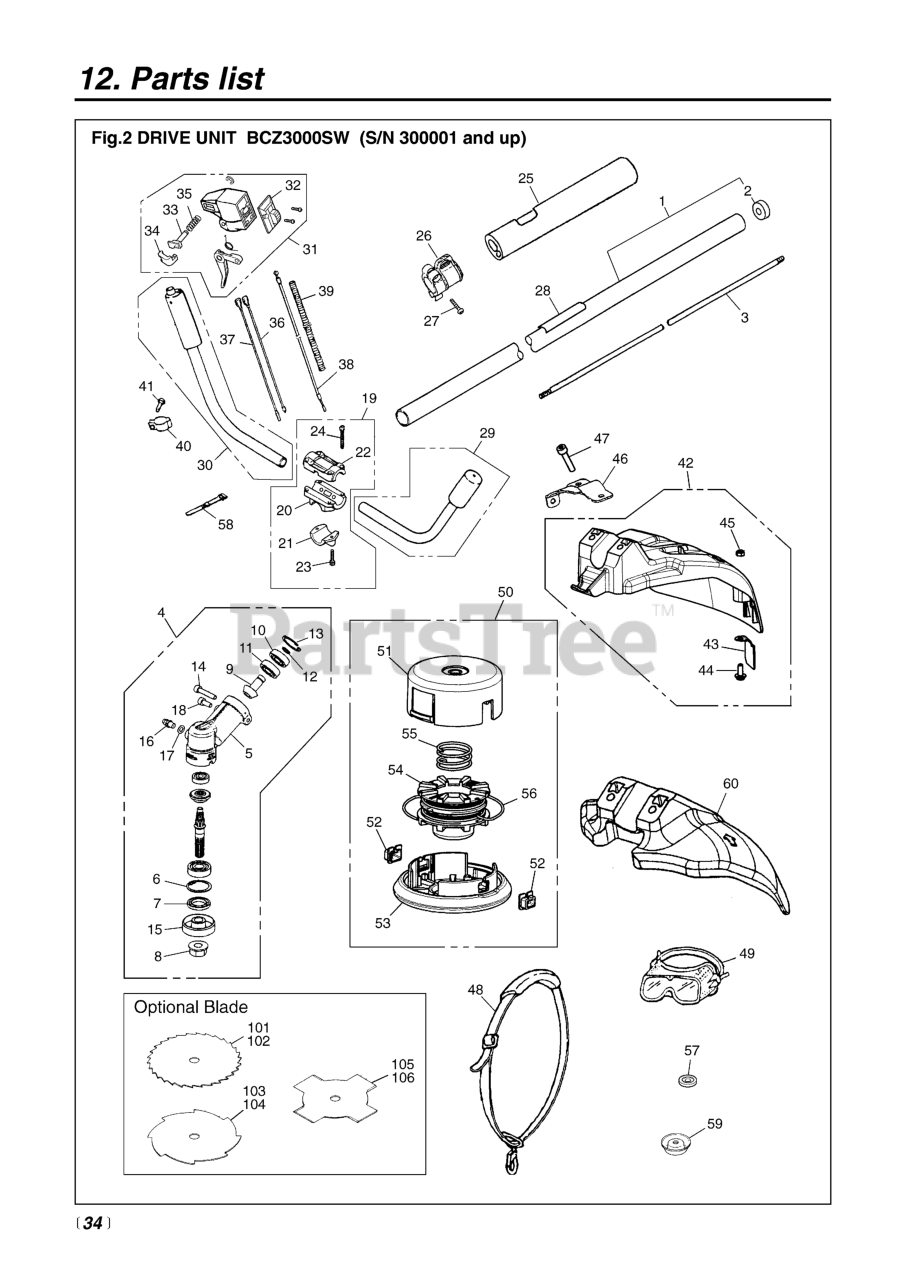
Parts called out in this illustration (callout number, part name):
1	PIPE COMP
2	SEAL
3	SHAFT (RPLS -12212)
4	GEARCASE ASSY.
5	GEARCASE
6	RING, SNAP, M26 X 1.2
7	SEAL, OIL
8	NUT
9	PINION
13	RING, SNAP, M24 x 1.2
14	BOLT, TORX
15	HOLDER (A)
16	FITTING, GREASE
17	WASHER, M6 X .8
18	BOLT, TORX
19	BRACKET ASSY.
21	CAP, LOWER
22	CAP, UPPER (RPLS -14191)
23	BOLT (RPLS 2850-14220)
24	BOLT, TORX
25	PROTECTOR
26	HANGER COMP.
27	SCREW
28	PLATE, NAME
29	HANDLE, L, COMP
30	HANDLE, R, COMP
31	LEVER ASSEMBLY
36	CORD (A), BLACK
37	CORD (B), RED
38	CABLE COMPLETE
39	TUBE
40	CLAMP
41	SCREW, M5 X 16
43	BLADE (RPLS T3002-24120)
44	SCREW TORX
45	NUT
46	BRACKET
47	BOLT, TORX
48	STRAP ASSY. (USE 848-JC0-3610)
49	GOGGLE
50	TAP HEAD COMP.
51	CASE (REPLACES -15111)
52	EYELET
53	COVER (REPLACES -15131)
54	HOLDER, CORD (REPLACES-15141)
55	SPRING
56	CORD
57	HOLDER (B)
58	BAND
59	COVER
60	GUARD
101	BLADE, 9
102	BLADE, 9
103	BLADE, 8
104	BLADE, 9
105	BLADE, 8
106	BLADE, 9
